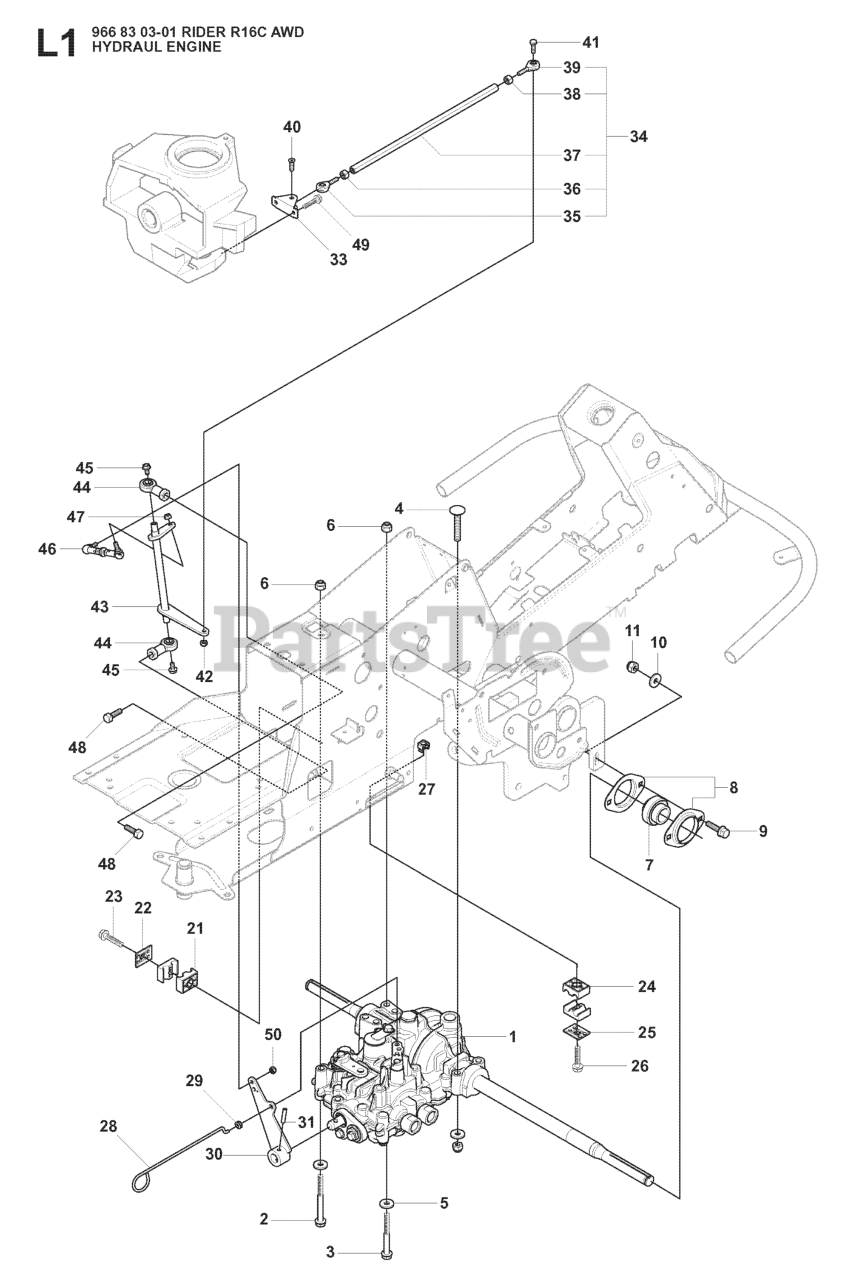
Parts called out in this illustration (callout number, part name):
1	%HYDRAULIC TRANSAXLE
5	WASHER BRB 8.4X17
6	LOCKNUT M8
7	BEARING
8	BEARING HOUSING
9	BOLT
10	WASHER BRB 8.4X17
11	LOCKNUT M8
21	PIPE CLAMP
24	PIPE CLAMP
25	COVER PLATE
26	SCREW EHHFM
29	FUEL TANK BUSHING
34	ROD
42	NUT FLANGE - M6
45	SCREW EHHFM
46	ADJUSTING ROD
47	NUT FLANGE - M6
48	Screw M10x25
50	LOCKNUT M6
